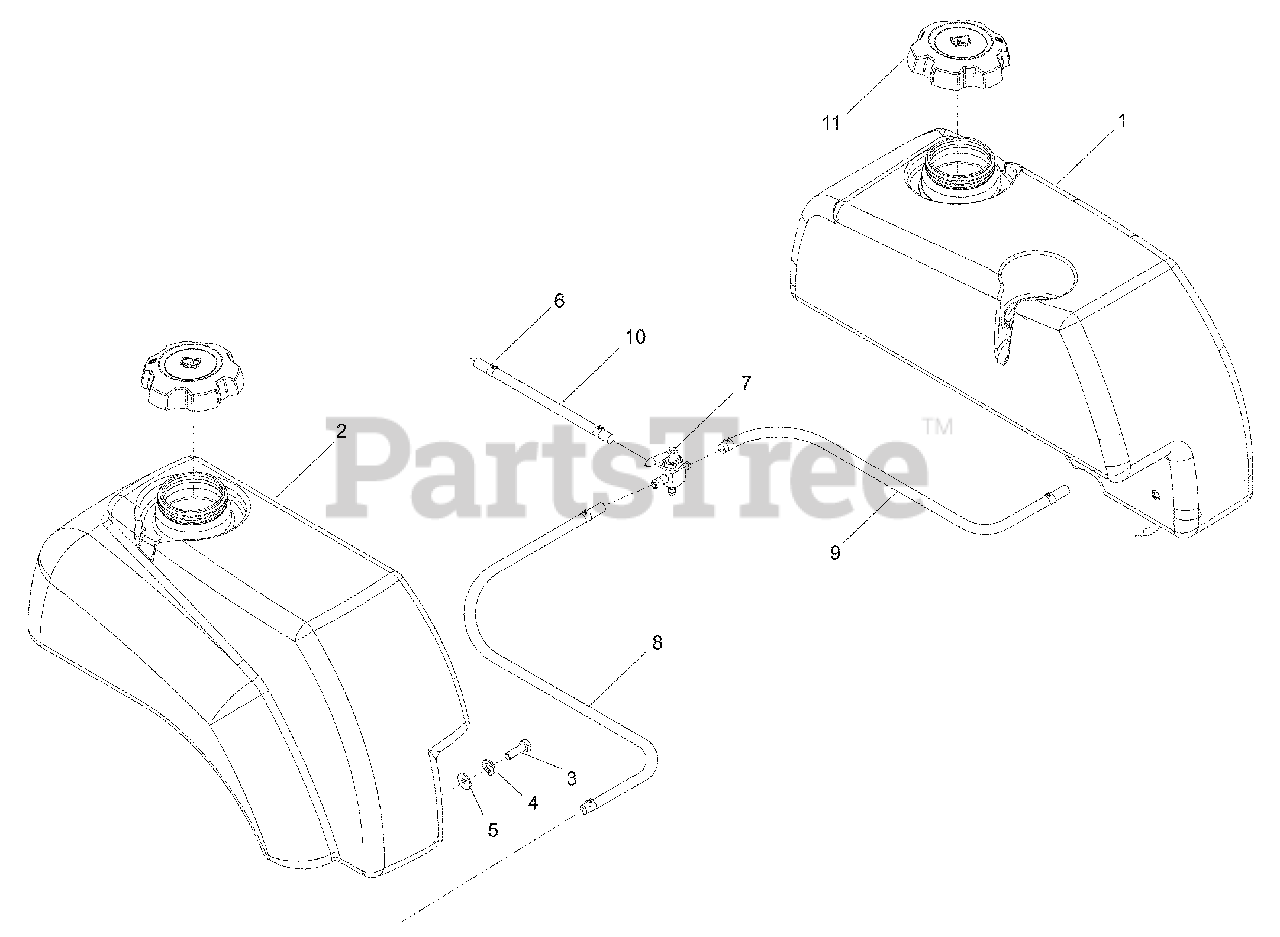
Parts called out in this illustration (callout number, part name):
1	FUEL TANK, LT
2	FUEL TANK, RT
3	HCS 5/16-18 x ¾
4	LOCKWASHER 5/16
5	WASHER 5/16 STD FLT
6	CLAMP, HOSE
7	VALVE, FUEL
8	HOSE, FUEL
9	HOSE, FUEL
10	HOSE, FUEL
